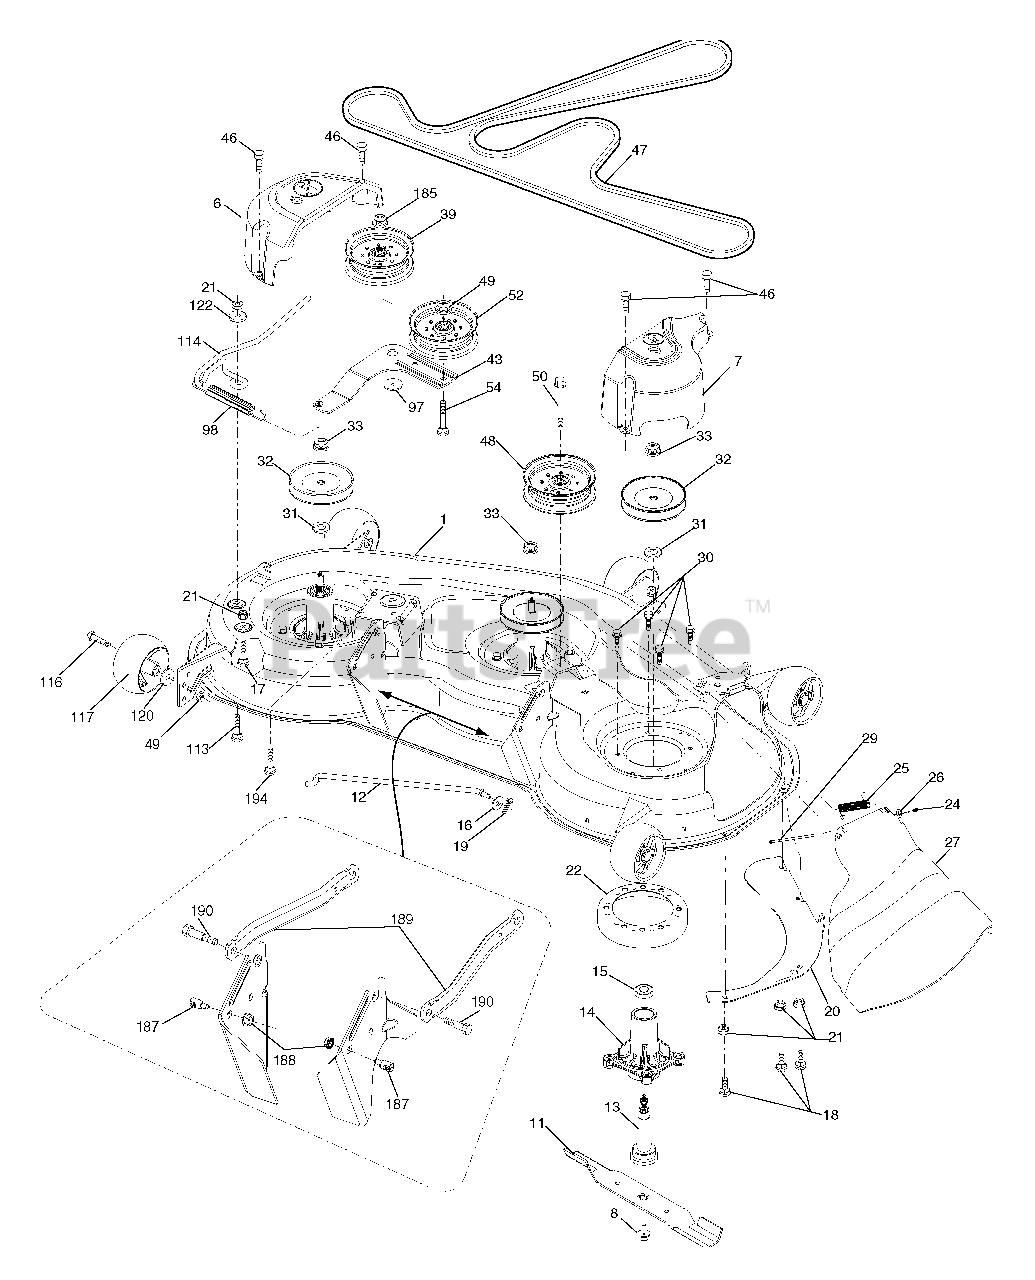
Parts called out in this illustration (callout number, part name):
1	Deck Weldment Mower
6	Cover Mandrel LH
7	Cover Mandrel RH
8	Bolt 7/16 Asm. Blade
8	Blade Mulching
11	Blade High Lift
12	Rod Anti-Sway
13	Shaft Asm. w/Lower Bearing
14	Housing, Mandrel
15	Bearing, Ball, Mandrel
16	Washer 13/32 x 13/16 x 12 Ga.
17	Bolt Carr. 5/16-18 x 5/8
18	Bolt Rd Hd 5/16-18 unc x 5/8
19	Pin Cotter 5/16 Bow Tie Lock
20	Baffle Vortex
21	Nut, Crownlock 5/16-18 unc
22	Stripper Mandrel Deck
24	Cap Sleeve
25	Spring, Torsion
26	Nut, Push
27	Deflector Shield
29	Rod, Hinge
30	Screw, Thdroll Washer Head
31	Washer, Spacer Mower Vented
32	Pulley, Mandrel
33	Nut, Flg. Top Lock
39	Pulley, Idler, Stationary
43	Arm, Idler
46	Screw, Thdroll. 1/4-20 x 5/8
47	V-Belt, Mower
48	Pulley Idler Primary
49	Nut, Lock Flg. 3/8-16 unc
50	Bolt Carr. SH 3/8-16 x 1-1/2
52	Pulley Idler Clutching
54	Screw 3/8-16 x 2-1/4 UNC
97	Washer Hardened
98	Spring Drive
113	Bolt Rdhd Sqnk 5/16-18 x 3/4
114	Rod Tension Relief
116	Bolt, Shoulder
117	Gauge Wheel
120	Washer 3/8 x 7/8 x 14Ga.
122	Bushing Tension Relief
185	Nut Lock Flange 7/16-14 Gr. 5
187	Stud Fastener w/"D" Anti-Rotation
188	Nut Lock Hex Flange 5/16-18
189	Arm Susp. Mower Rear
190	Bolt Shoulder
194	Bolt Carr Sqnk 3/8-16 x 2-1/4
